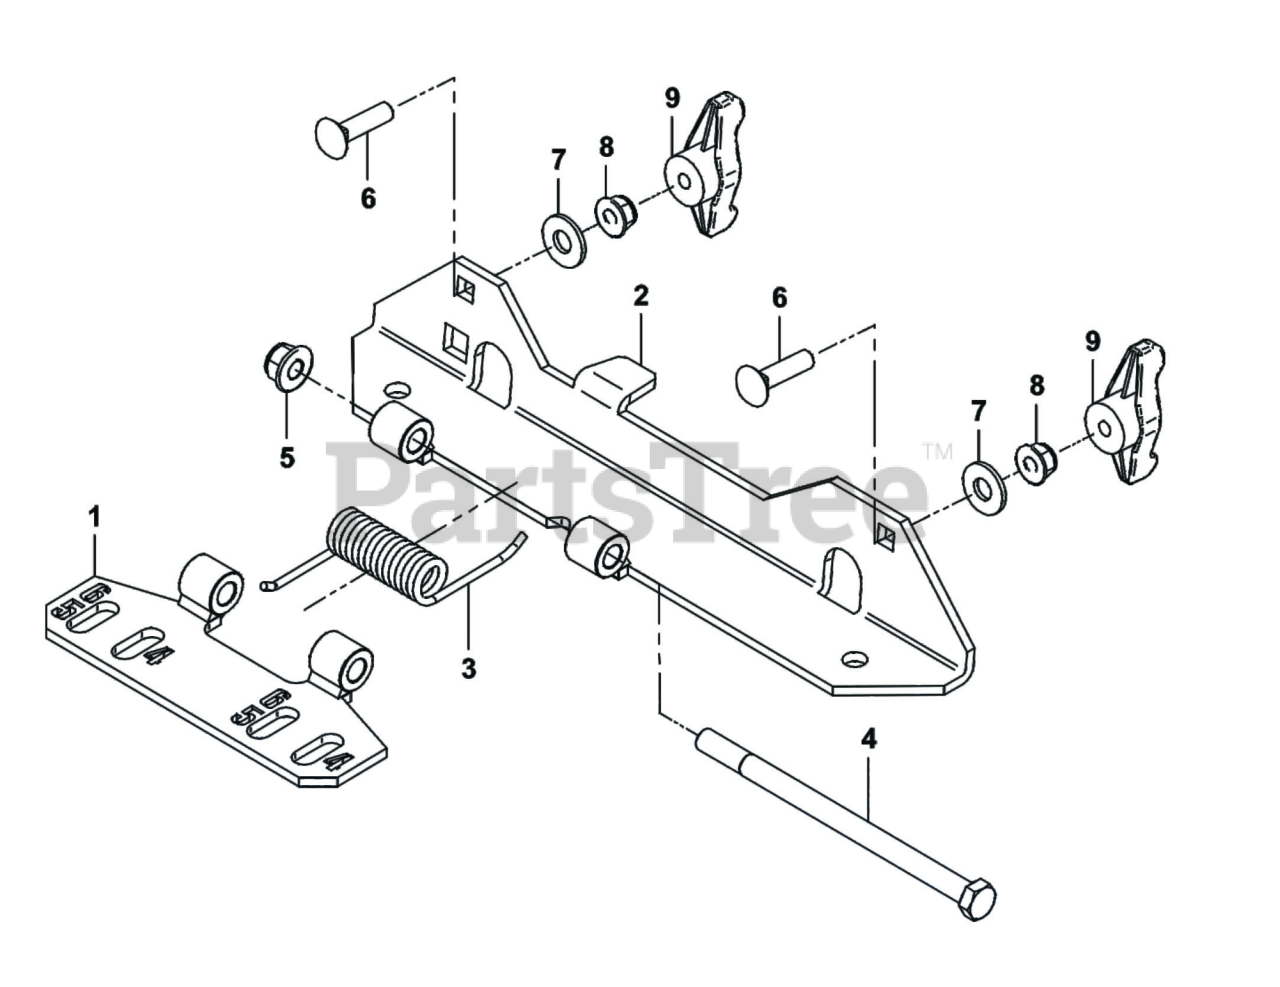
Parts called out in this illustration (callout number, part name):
1	BOOT PLATE ASSEMBLY
2	DECK PLATE ASSEMBLY
3	TORSION SPRING
4	SCREW 3/8"-16 x 6" (GR5)
5	LOCKNUT-NYLON FLAN
6	CARRIAGE BOLT 5/16"-18 X 1.25"
7	FLAT WASHER
8	NUT-FLANGE LOCK 5/
9	WING KNOB (5/16"-18)
